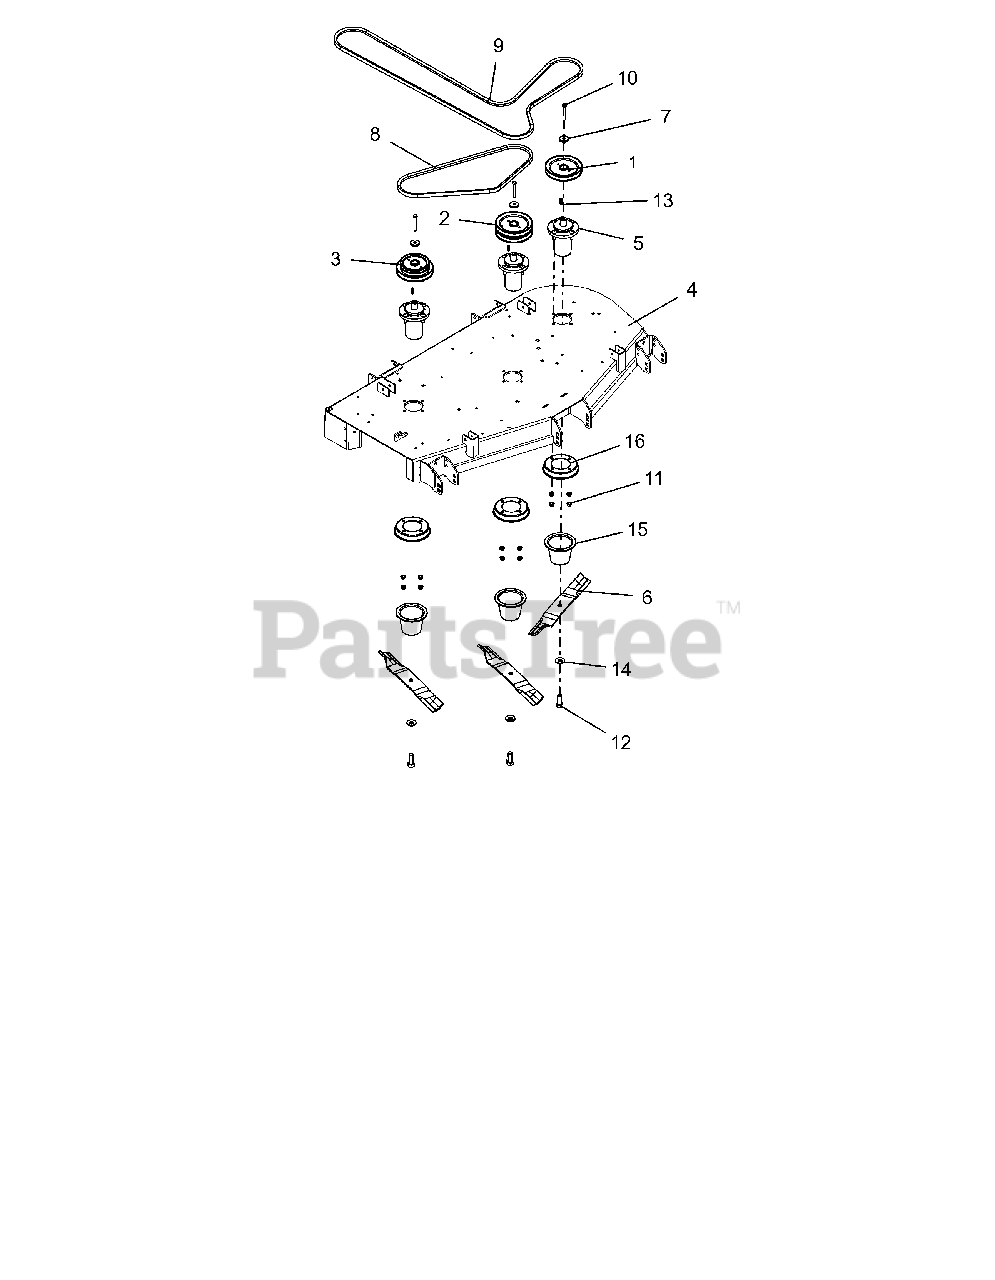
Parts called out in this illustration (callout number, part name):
1	PULLEY, SINGLE-1"ID X 6" OD
2	PULLEY, DOUBLE
3	PULLEY, DBL-1"IDX6.00"&4.75"OD
4	52"SIDE DISCH DECK WMT W/SAFE
5	ASM, MAINT FREE ALUM SPINDLE
6	BLADE, 18.00" MOWER (HI-LIFT)
7	RETAINER, SHEAVE
8	V-BELT, B-COGGED
9	V-BELT, HB RAW EDGE EPDM
10	BLT-HEX .38-16X2.75 GR8 YWZC
11	NUT-LK-CTR-FLG .38-16 YWZC
12	BLT-HEX .62-18X1.75 GR8 YWZC
13	KEY, SQ .25X.25X1.00 RC 40-50
14	WSHR-BLVL .669X1.535X.138
15	GUARD, SPINDLE LOWER
16	GUARD, SPINDLE TOP
